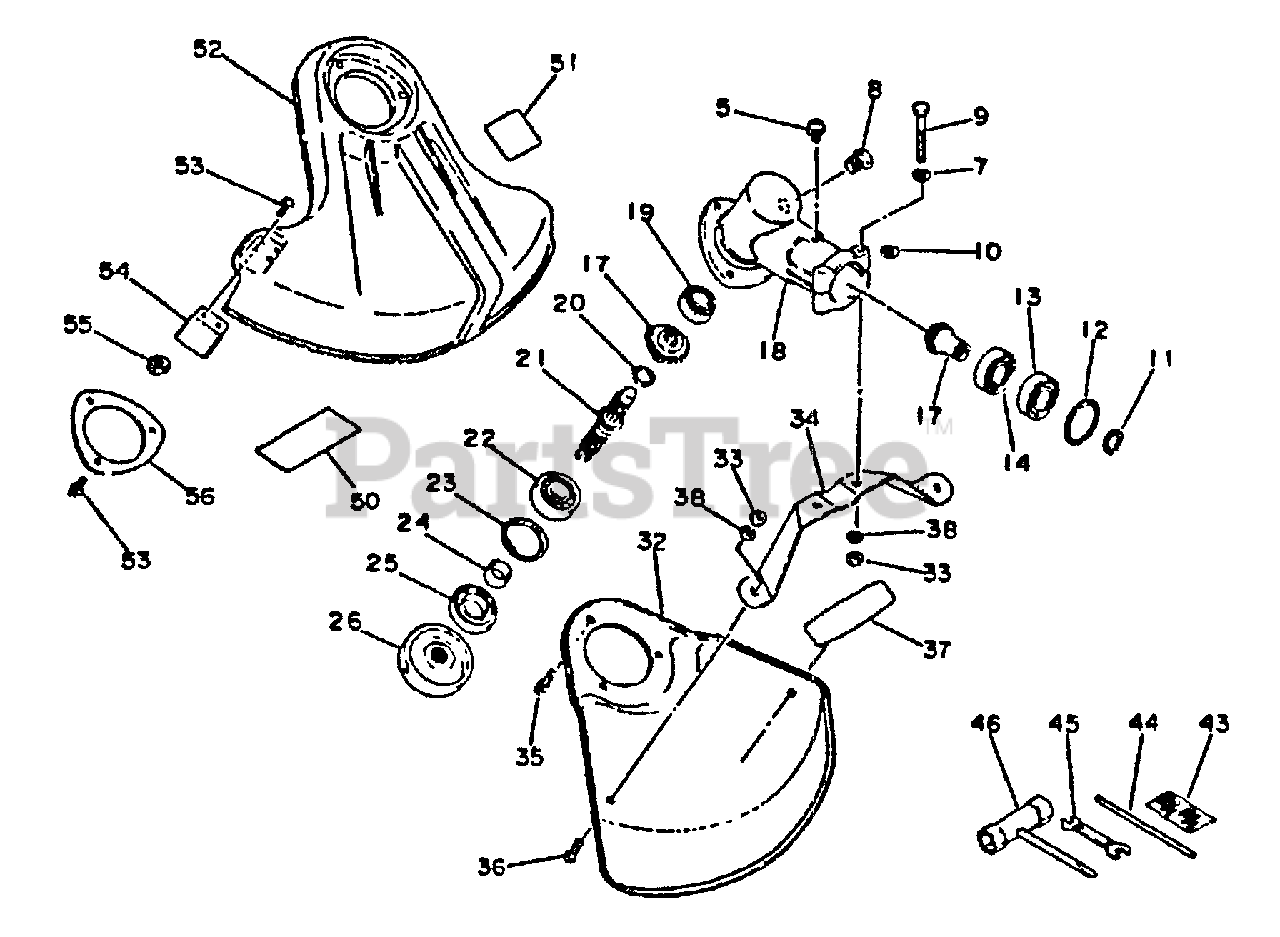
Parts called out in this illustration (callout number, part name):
5	SCREW - 5X10
7	WASHER - 5
8	BOLT - 8X8
9	BOLT - 5X40
11	RING, RETAINING - 12
12	RING, RETAINING - 28
13	BEARING, BALL - 6001
14	BEARING, BALL - 6001
17	GEAR SET - BEVEL
18	CASE, GEAR
19	BEARING, BALL - 6000
20	RING, RETAINING
21	GEAR - SHAFT
22	BEARING, BALL - 6201
23	RING, RETAINING - 32
25	SEAL, OIL
26	ADAPTOR, BLADE - UPPER
32	SHIELD
34	BRACKET, SHIELD
35	SCREW - 5X10
36	SCREW - 5X8
37	LABEL - ECHO
38	LOCKWASHER - 5
43	PIN, SPLIT - 2X22
44	LOCKING TOOL
45	SPANNER - 8X10mm
46	T-WRENCH - 17X19mm
50	LABEL - ECHO
51	LABEL - CAUTION
52	SHIELD, DEBRIS
53	SCREW - 5X16
54	KNIFE, TRIMMER LINE
56	PLATE, SHIELD
